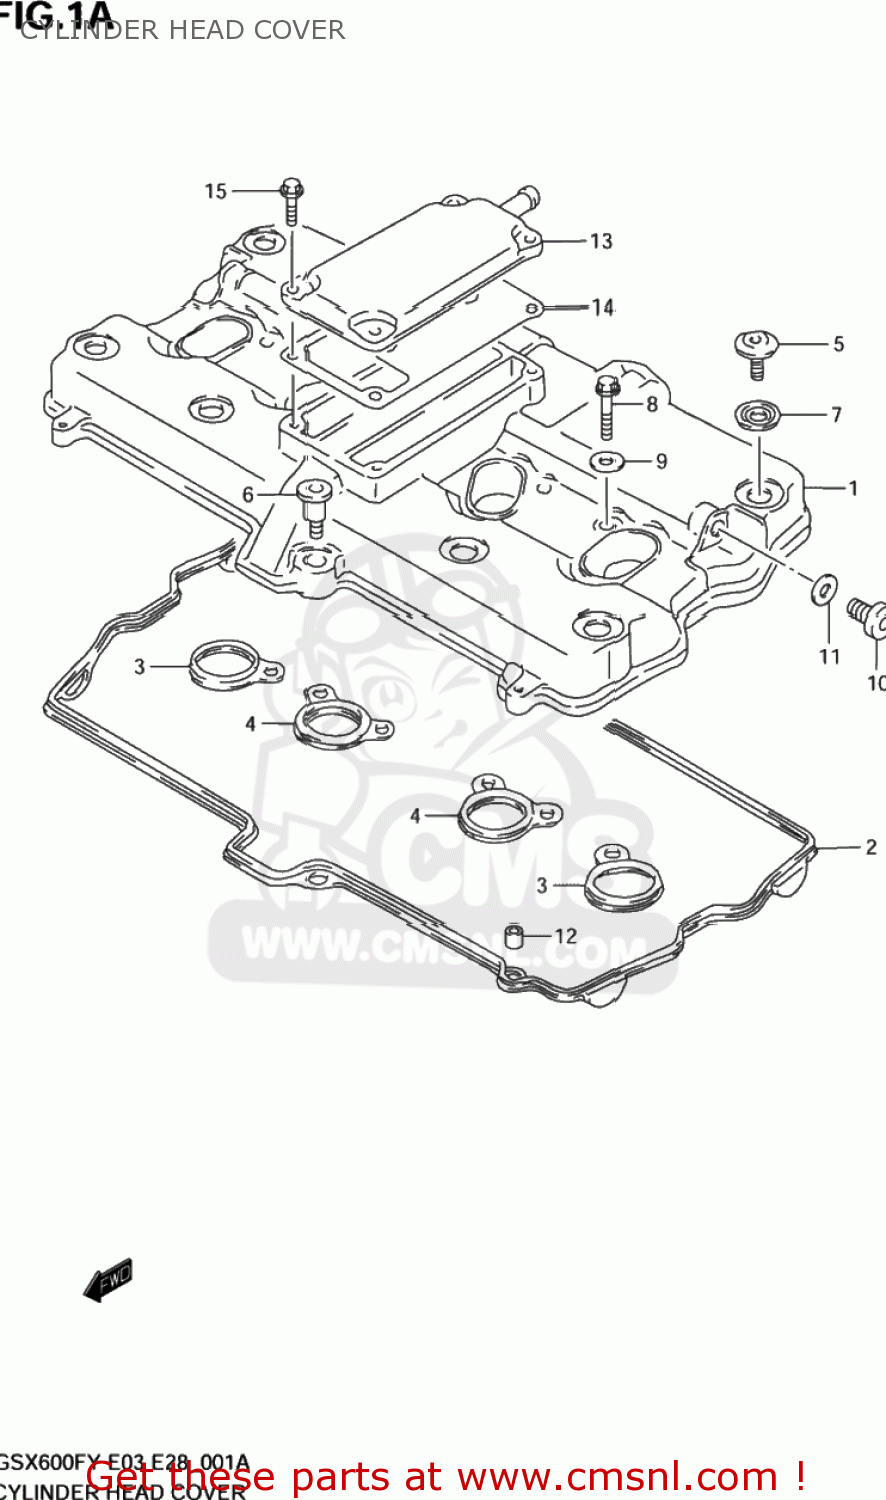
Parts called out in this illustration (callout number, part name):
1	COVER,CYLINDER HEAD
2	GASKET,CYLINDER HEAD COVER (NAS)
3	GASKET,HEAD COVER NO.2 (NAS)
4	GASKET,HEAD COVER NO.3 (NAS)
5	BOLT(7X17.5)
6	BOLT(7X31)
7	WASHER(10.6X25.5X2.3)
8	BOLT,UNION 8X35
9	GASKET 8.2X14X1 (NAS)
10	PLUG(L:12)
11	GASKET(12.1X16.2X3.7) (NAS)
12	PIN
13	COVER,BREATHER
14	GASKET,BREATHER COVER (NAS)
15	BOLT
